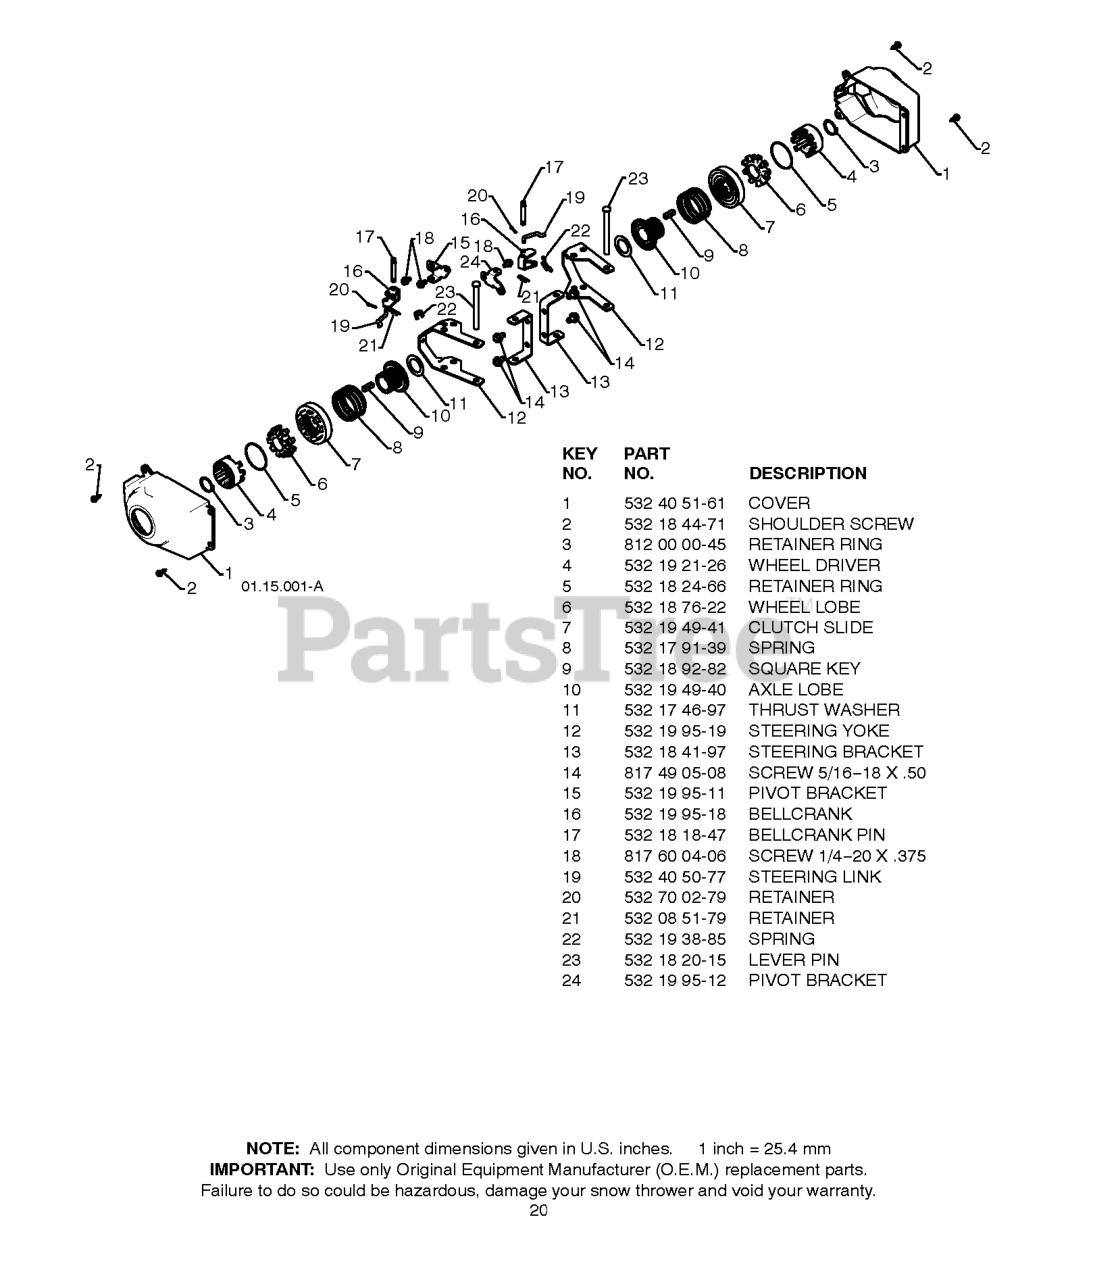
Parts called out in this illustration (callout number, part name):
1	COVER, POWER STEERING
2	SCREW, HEX HEAD, TAPPING
4	RP.DRIVER WHEEL
5	RING, WIRE RETAINER
6	LOBE WHEEL
7	RP.SLIDE.CLUTCH
8	SPRING, CLUTCH SLIDE
9	KEY, SQUARE 1/4 X .875
10	RP.LOBE.AXLE
11	WASHER TRUST 1"
12	YOKE, STEERING
13	BRACKET.STEER.PNT.BLACK
14	Screw 5/16-18 x 1/2 Hex, Self Tapping 5/16-18 x 1/2
15	BRKT.STEER.PIVOT.RH
16	BELLCRANK.STEER
17	PIN, STEERING BELLCRANK
18	SCREW 1/4X20
19	LINK.STEER.YOKE
20	RETAINER CLIP
21	RETAINER CLIP PM
22	SPRING LATCH
23	PIN, STEERING LEVER
24	BRACKET.STEER.PIVOT.LH.YZ
